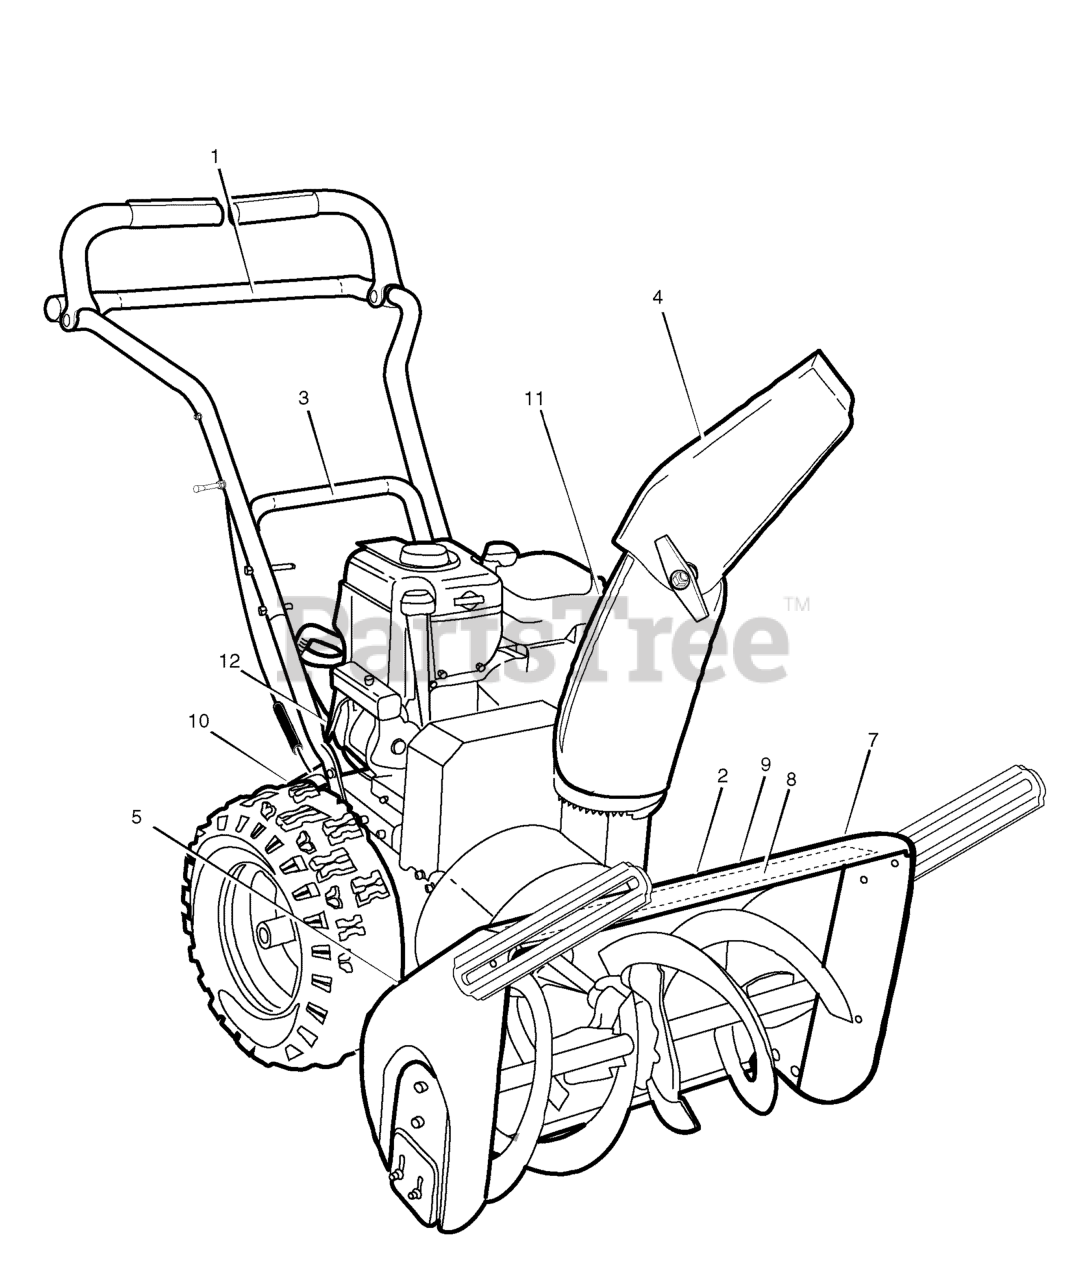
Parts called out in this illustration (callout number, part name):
1	DECAL, TRACTION AUGER DRIVE
2	DECAL, CLEANOUT BRUSH
3	DECAL, GEAR SELECT
4	DECAL, DANGER THROWN OBJECTS
5	DECAL, ISO AUGER
7	DECAL, FACE HEAD PHONES
8	DECAL, LOWES, TOP AUGER
9	DECAL, 104db CE
10	DECAL, ID PLATE
11	DECAL, DANGER CHUTE
12	DECAL, OVER ADJUST
